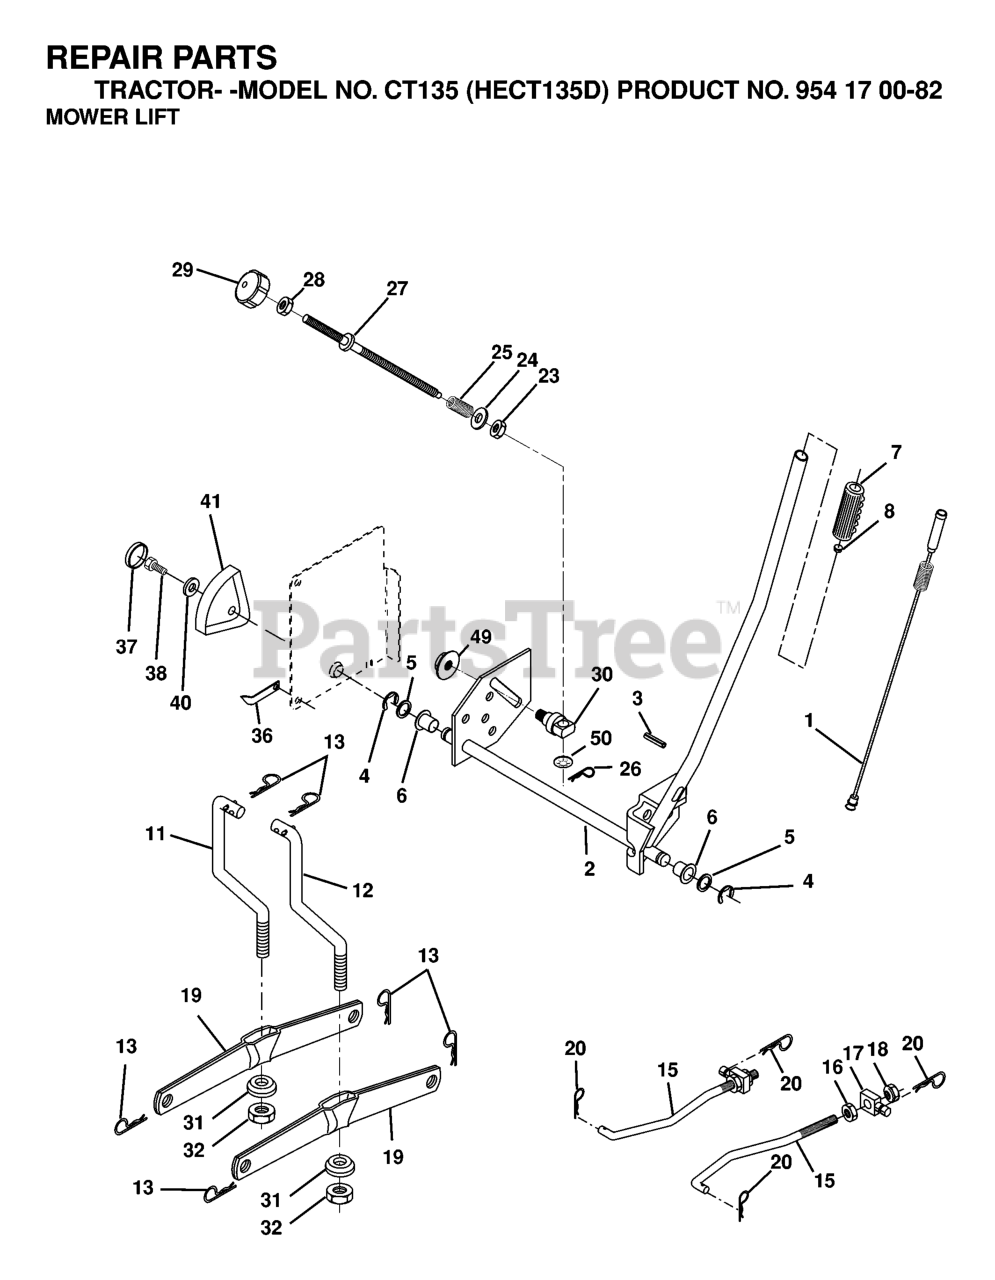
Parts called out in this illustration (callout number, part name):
1	WIRE ASM INNER W/ PLUNGER LT
2	SHAFT ASM R HANDLE
3	PIN GROOVE.
4	RETAINING RING LT
6	BEARING.NYLON
7	GRIP HANDLE
8	PLUNGER BUT KIT
11	LINK
12	LINK
13	RETAINER-SPRNG RB
15	LINK.SUSPENSION.FRONT
16	NUT.HEX.JAM.1/2-13
18	NUT.LK.W/WSH.1/2.
19	ARM.REAR.SUSPENSION
20	SPRING RETAINER
25	SPRING**
26	RETAINER CLIP
27	ROD ADJ LIFT
28	NUT
29	KNOB INF 3/8-16
31	BEARING.PIVOT.LIFT
32	NUT CROWNLOCK 3/8-24
36	POINTER, HEIGHT INDICATOR(2 2)
38	SCREW 5/16-18X1
41	HEIGHT INDICATOR
49	NUT
50	NUT PUSH M
